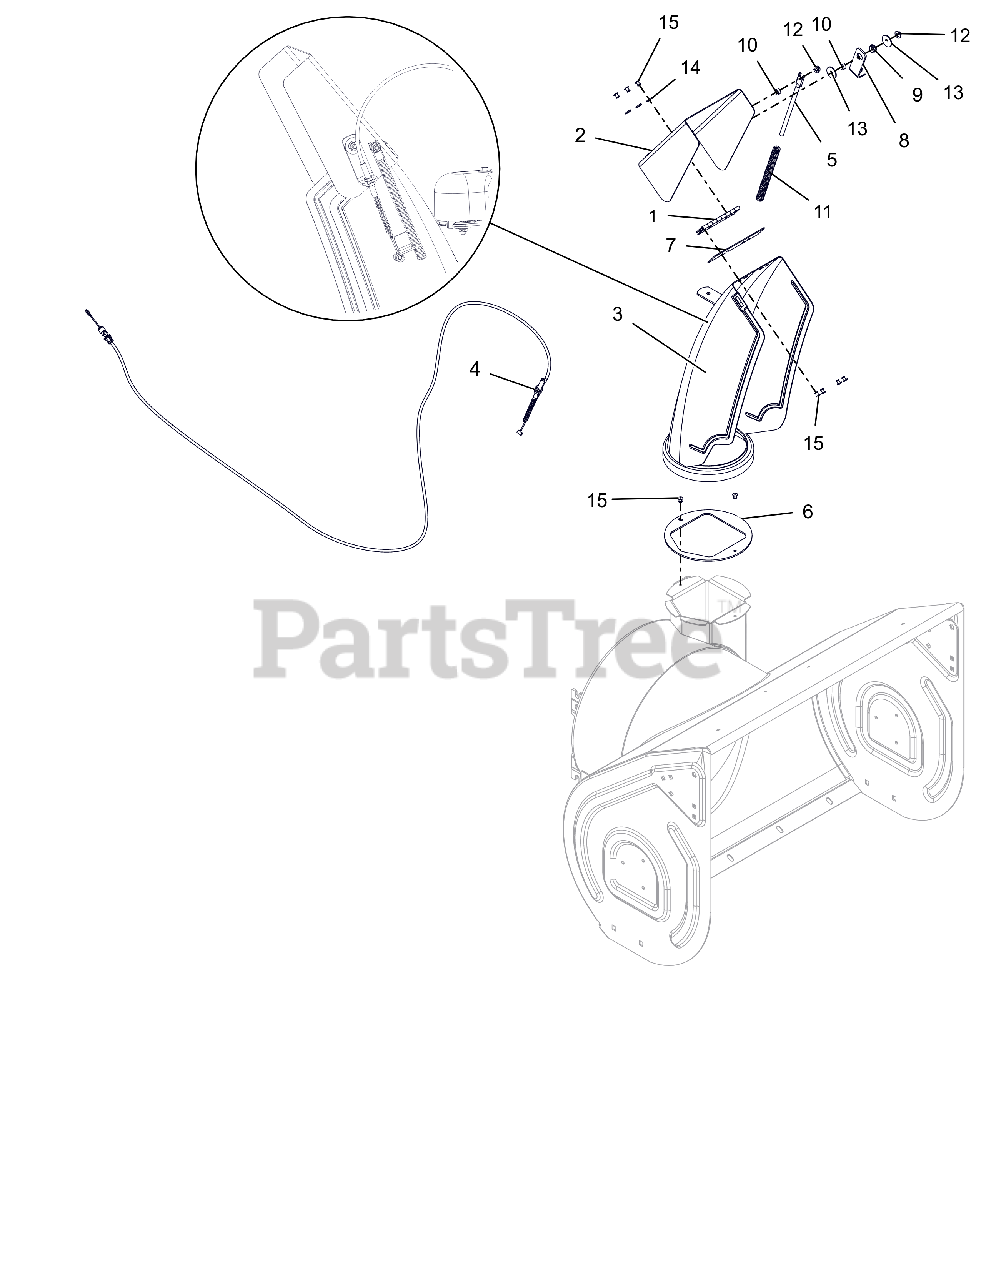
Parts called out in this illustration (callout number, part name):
2	CAP, LARGE REMOTE (W/DECAL)
3	CHUTE,DISCHARGE,NOTCHED,QT
4	CABLE, DEFLECTOR - DELUXE
5	ROD, DEFLECTOR CAP
6	BAFFLE, DISCHARGE NECK
7	CAP SEAL 5.50
8	BRACKET, CABLE ANCHOR
9	BUSHING, POLYLINER-.50 SNAPIN
10	BSHG-SLV .265X.500X.219
11	SG-COMP .08X.40X6.50 14#/IN
12	@NUT-LK-CTR-FLG .25-20 YWZC
13	WSHR-FL-STL .281X1.000X.063
14	WSHR-FL-STL .196X.500X.06 YZ
15	RVT-POP .187 YZ
